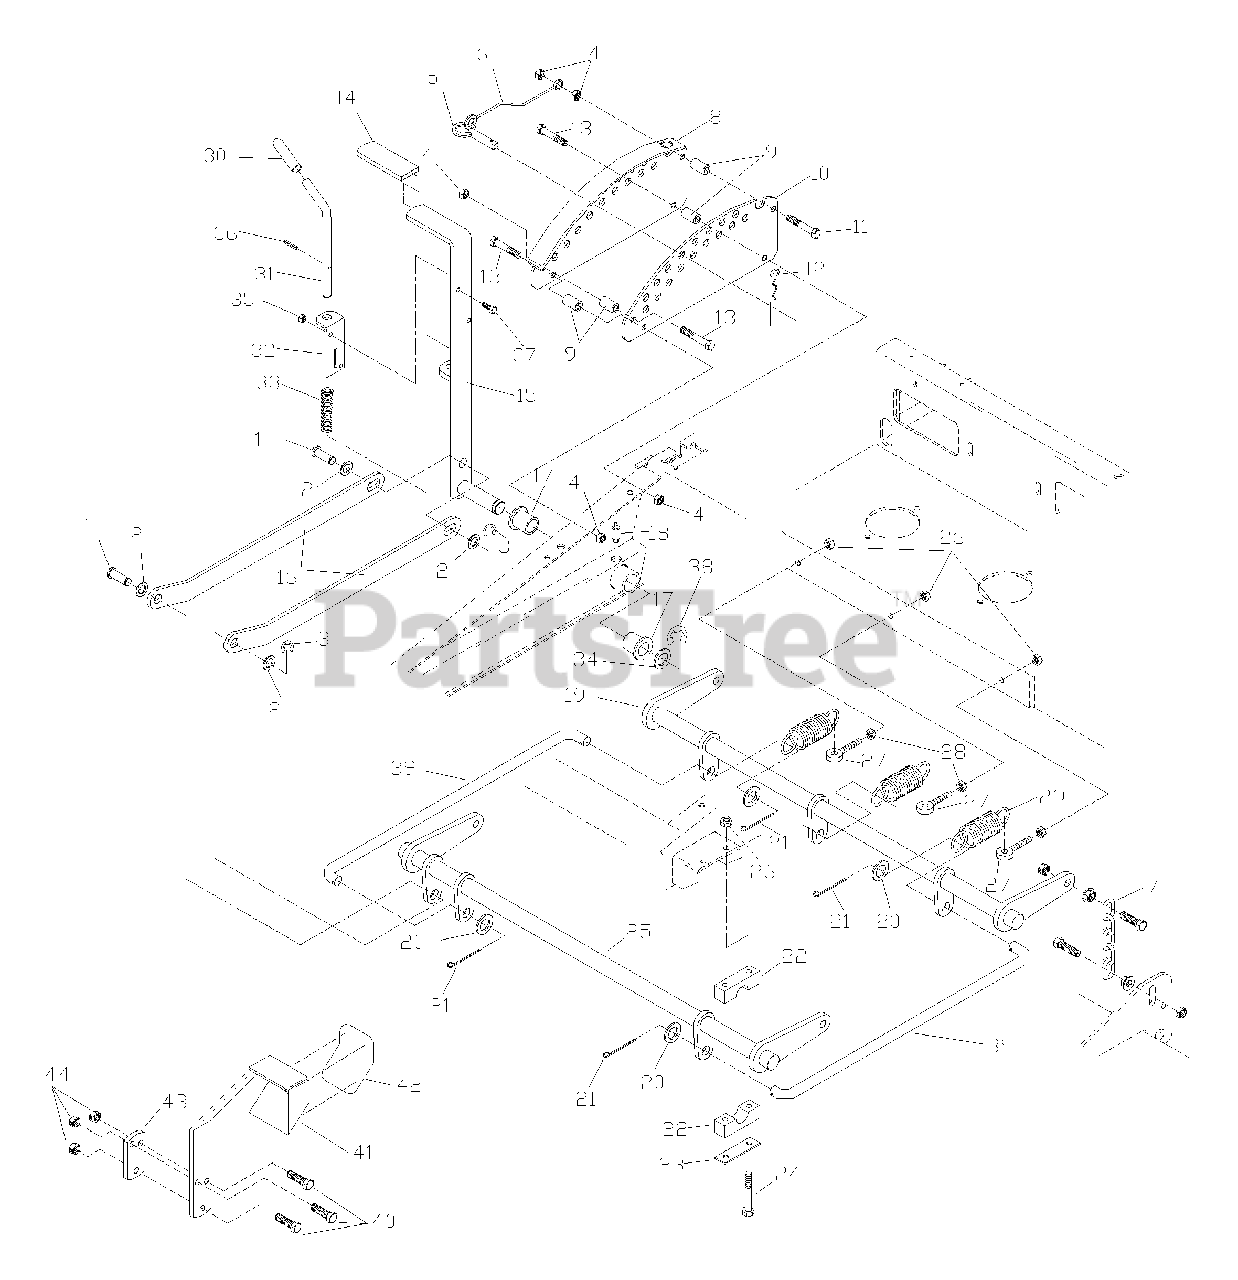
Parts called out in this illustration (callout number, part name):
1	CLEVIS PIN
2	MACH BUSHING
3	5/8 E - RING
4	NUT 3/8C CTR LOCK
7	LIFT CHAIN
8	ADJ PLATE WLDMT
9	DECK LIFT SPACER
10	ADJ PLATE PAINTED
11	HCS 3/8C X 2.5
12	# 4 HAIR PIN
13	HCS 3/8C X 2.25
15	LEVER WLDMT
16	LIFT LINKAGE
17	FLANGE BUSHING
18	ZERK - LONG
19	LIFT SHAFT, REAR
20	5/8 SAE WASHER
21	COTTER PIN
22	PILLOW BLOCK
23	SUPPORT PLATE
24	HCS 5/16C X 2.5
25	LIFT SHAFT, FRONT
26	NUT 5/16C CTR LOCK
28	5/16C WHIZ NUT
29	DECK LIFT SPRING
32	PIN MT, UPPER
34	MACH BUSHING
35	NUT 1/4C CTR LOCK
36	3/16 X 1 ROLL PIN
37	HCS 1/4C X 3/4
38	7/8 E - RING
40	HCS 3/8 X 1.5
41	LIFT PEDAL
42	ANTI-SKID PAD
43	TIGHTING PLATE
44	NUT 3/8 NYLOC
